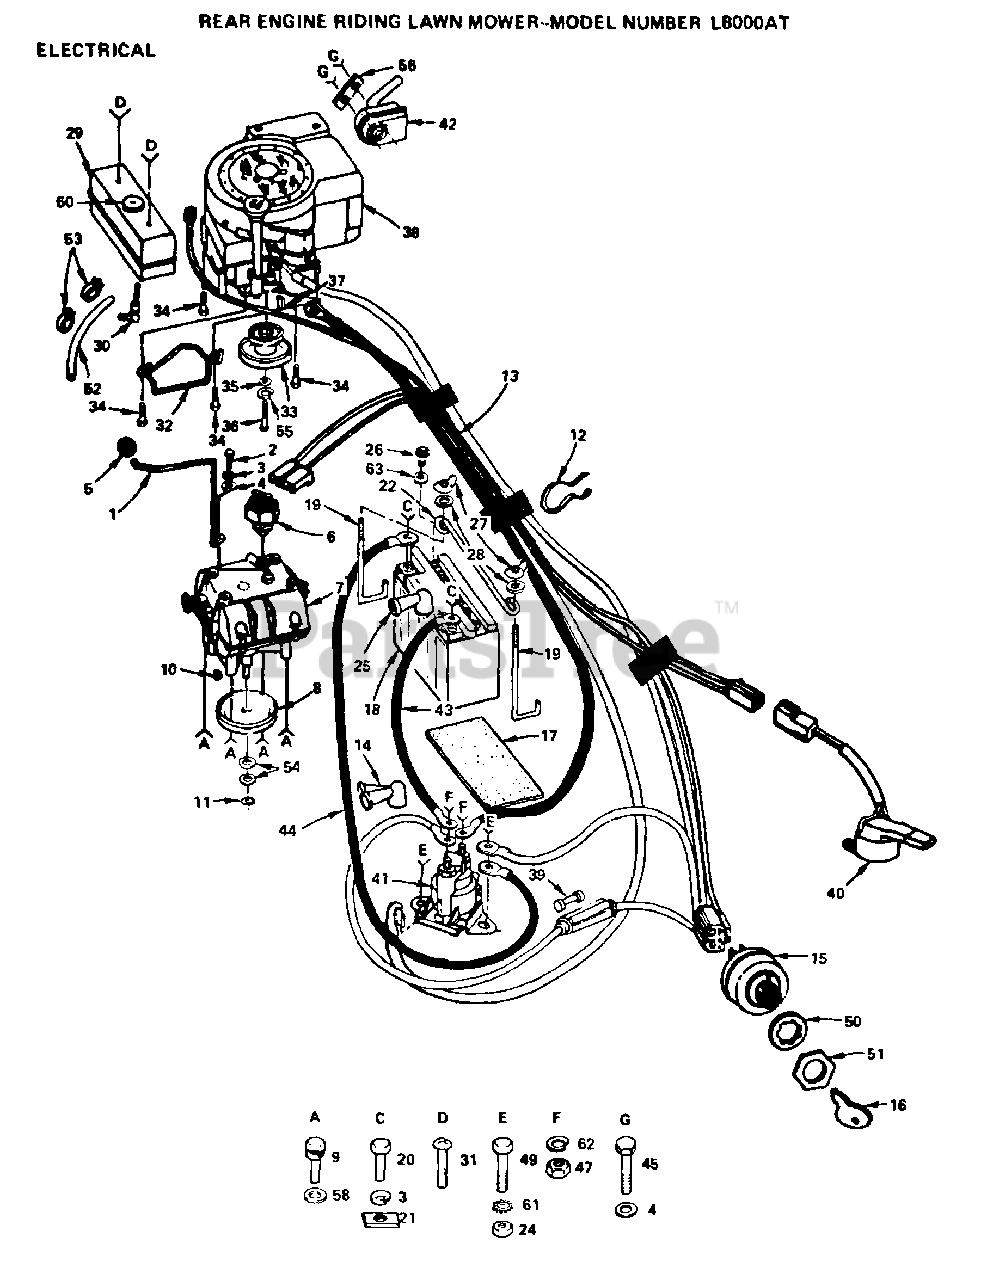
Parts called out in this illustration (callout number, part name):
1	SHIFT LEVER T
2	BOLT
4	WASHER PM
7	TRANSMISSION ASSY
8	TRANS PULLEY
12	WIRE TIE
14	TERM COVER DUAL
17	PAD - BATTERY
22	"ROD LT, BATTERY"
26	CAP - BATTERY
28	WASHER
31	SCREW
33	ENGINE PULLEY RER
34	SCREW LT
35	WASHER LT
36	BOLT RER
37	SQ KEY STD
39	FUSE - 15 AMP
40	No Desciption for Part
44	CABLE ASSY LT
47	NUT
49	BOLT LT
50	LOCKWASHER
51	CONDUIT NUT L
52	HOSE T
54	WASHER
55	LOCKWASHER
56	MUFFLER CLIP T
60	CAP-FILLER T
63	GASKET - BATTERY
